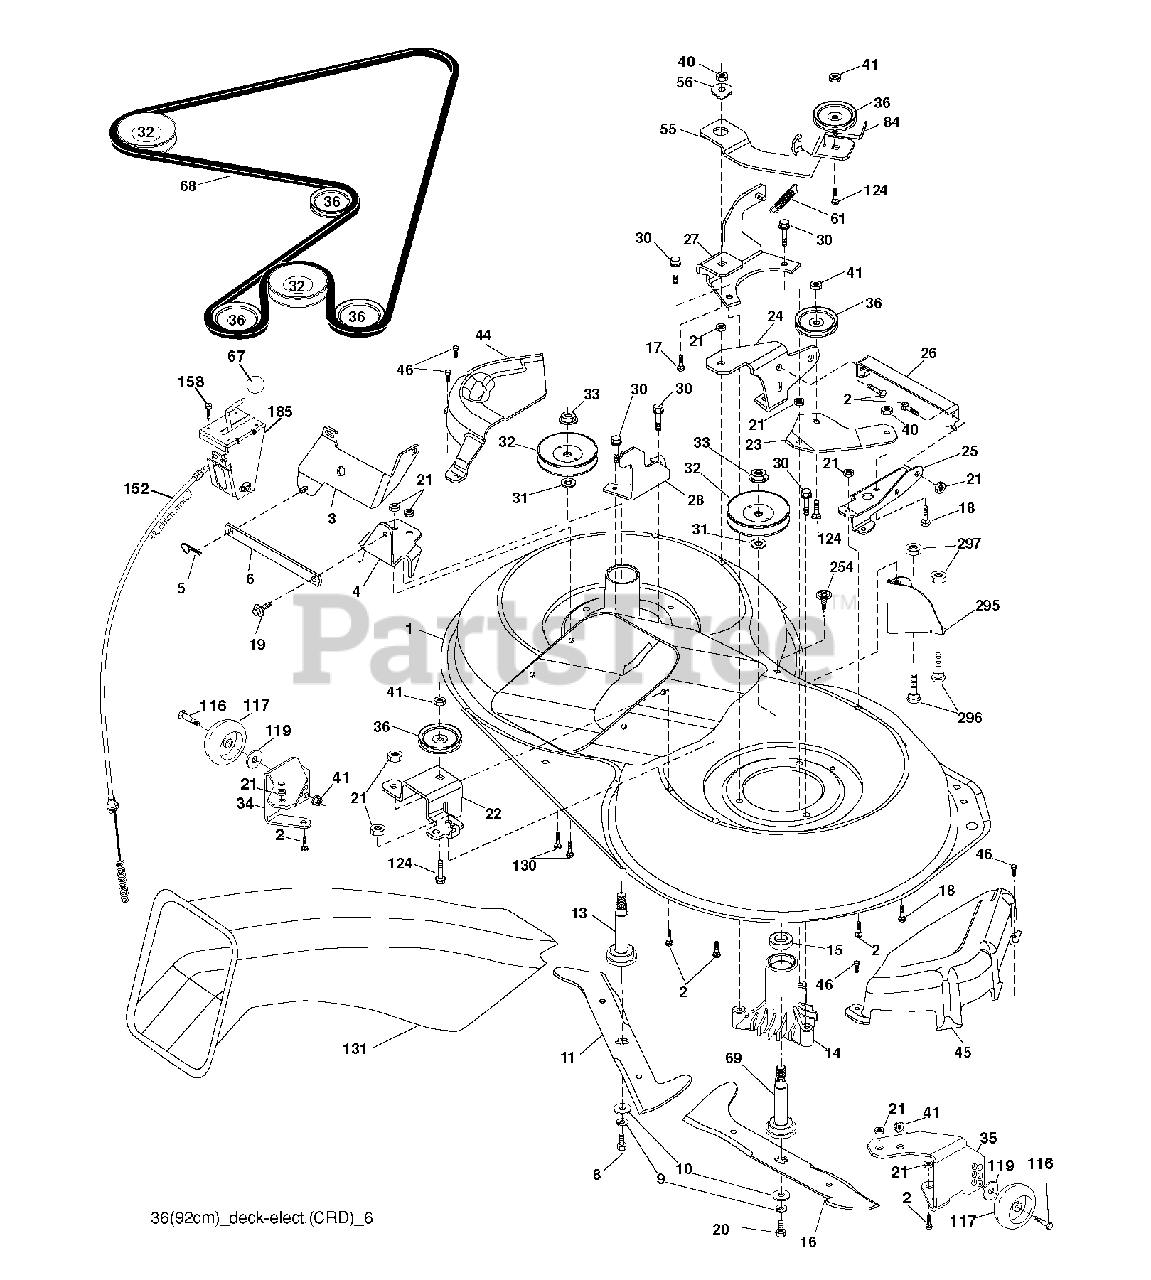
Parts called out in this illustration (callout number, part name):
2	BOLT
3	BRACKET
5	RETAINER-SPRNG RB
6	BAR SWAY
9	LOCKWASHER
10	WASHER.BLADE
13	SHAFT ASM VENT
14	HSG MANDREL
17	BOLT.3/8-14X1.25
19	BOLT SHD 5/16-18
21	LOCKNUT
24	BRACKET
25	BRACKET
28	BRACKET
30	SCREW, WASHER HEAD
31	WASHER.SPACER.MANDREL
32	PULLEY MANDREL
33	NUT.FLANGE.LOCK.TOP
36	PULLEY.IDLER.4.25
40	LOCKNUT
41	NUT LOCK FLG 3/8-16 UNC
45	MANDREL COVER
46	SCREW.1/4-20X5/8
56	SPACER.RETAINER.MOWER
67	KNOB T (3/8 HOLE)
69	SHAFT.ASM.W/LWR.BRG.RH.THREAD
84	KEEPER, BELT IDLER
116	BOLT.SHOULDER.3/8-16X3-5/8
117	WHEEL. GUAGE RALLY
124	BOLT.3/8-16X1.50
131	CHUTE BAGGER
158	SCREW
185	HEAD ASM. CABLE CLUTCH
254	SCREW 3/8-16X1
296	BOLT
297	NUT CENTERLOCK
